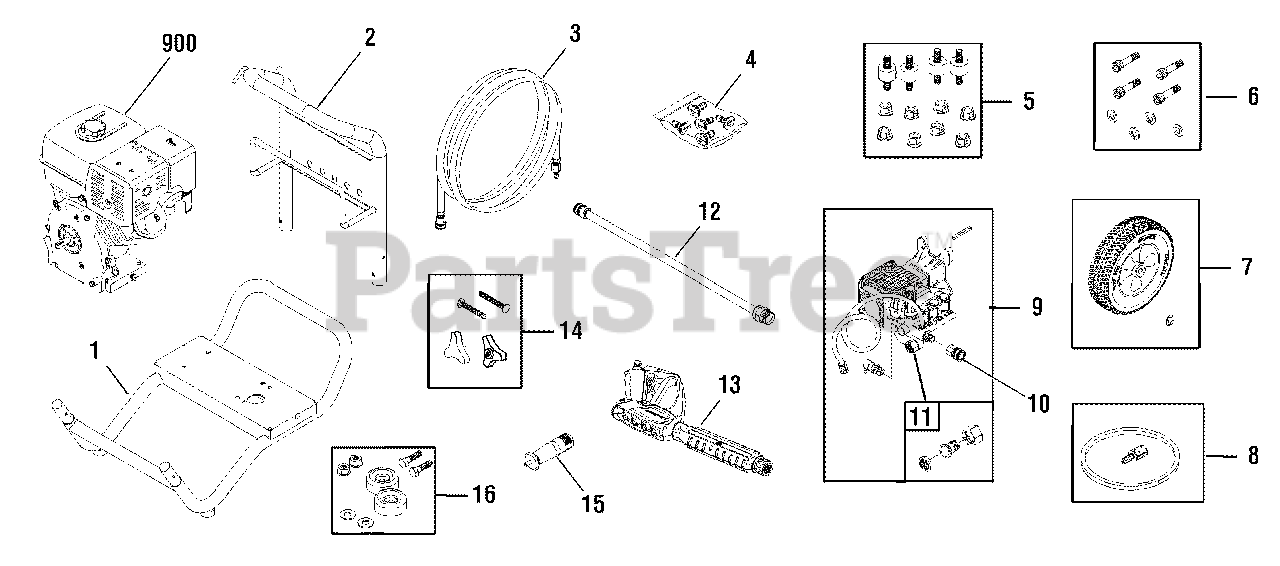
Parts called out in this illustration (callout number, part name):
4	KIT, QC Nozzle
5	KIT, Hardware, Engine Mounting
6	KIT, Hardware, Pump Mounting
9	PUMP
10	FITTING
11	ADAPTER, Garden Hose
13	EXTENSION, QC
14	KIT, Hardware, Handle
16	MOUNT, Vibration
900	* ENGINE
